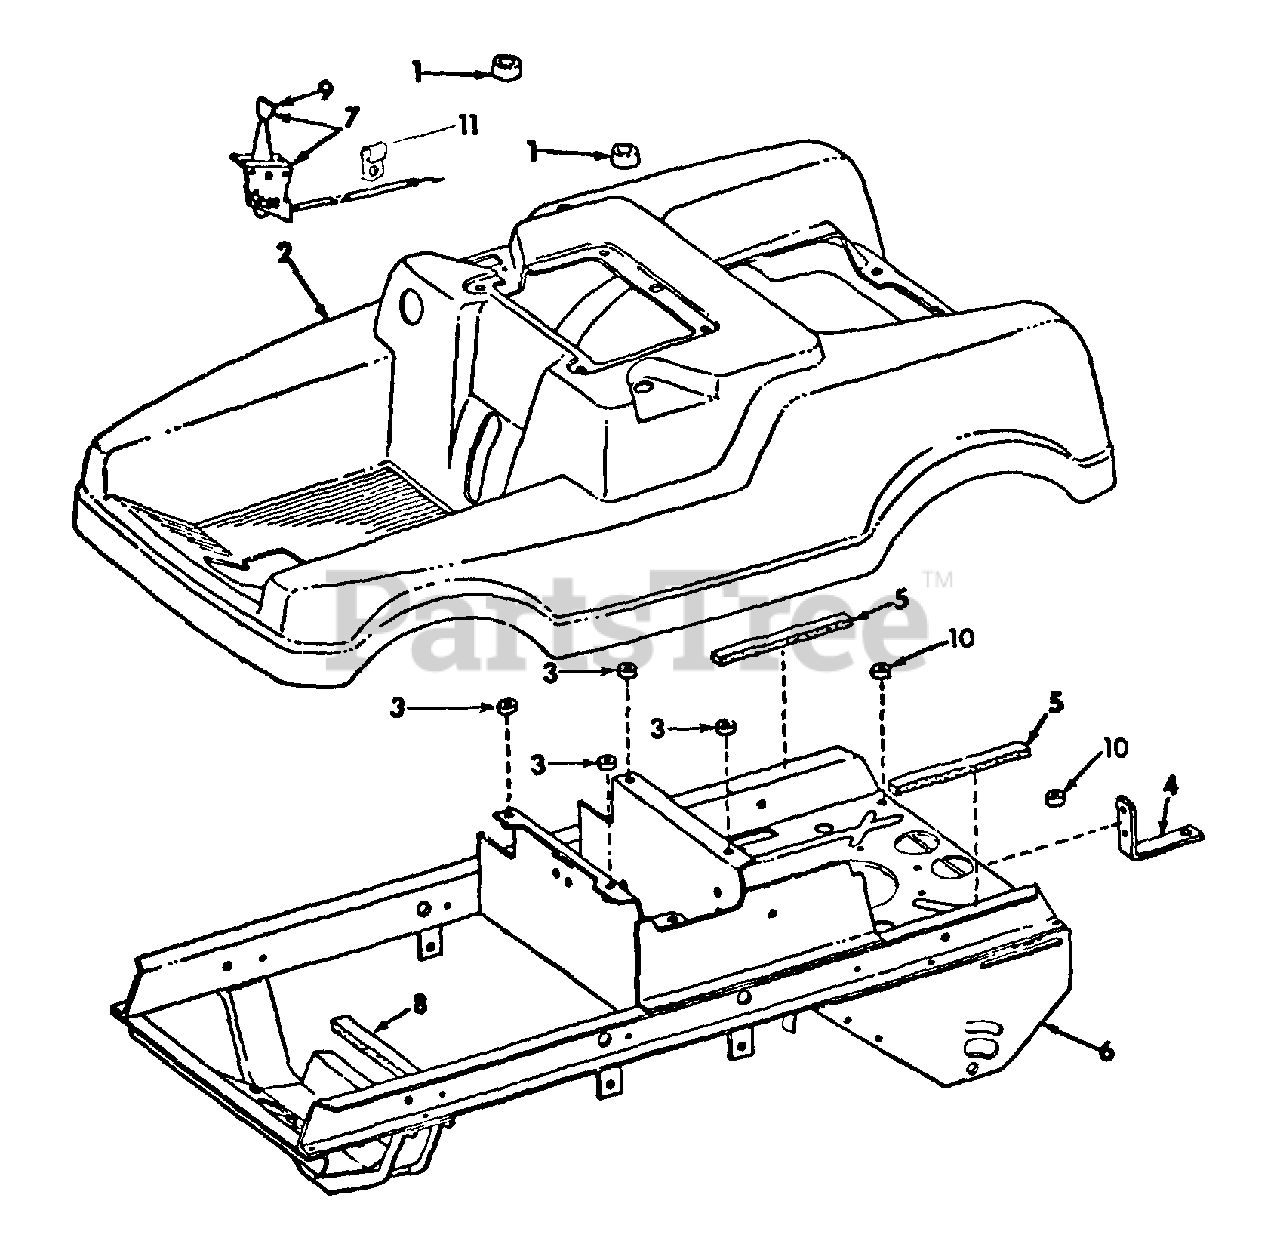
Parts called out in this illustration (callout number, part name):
1	BUMPER, SEAT SUPPORT REAR
2	BODY W/PLUG, 432 485 AND PLUG, 432 580
3	SPACER, BODY MOUNTING
4	ANGLE, DRAWBAR
5	SEAL, PRESSURIZED
6	FRAME W/PRODUCT GRAPHIC, MAIN
7	CONTROL, THROTTLE
8	SEAL, PRESS FRT REST
9	KNOB, THROTTLE CONTROL
10	SPACER, BODY MTG REAR
